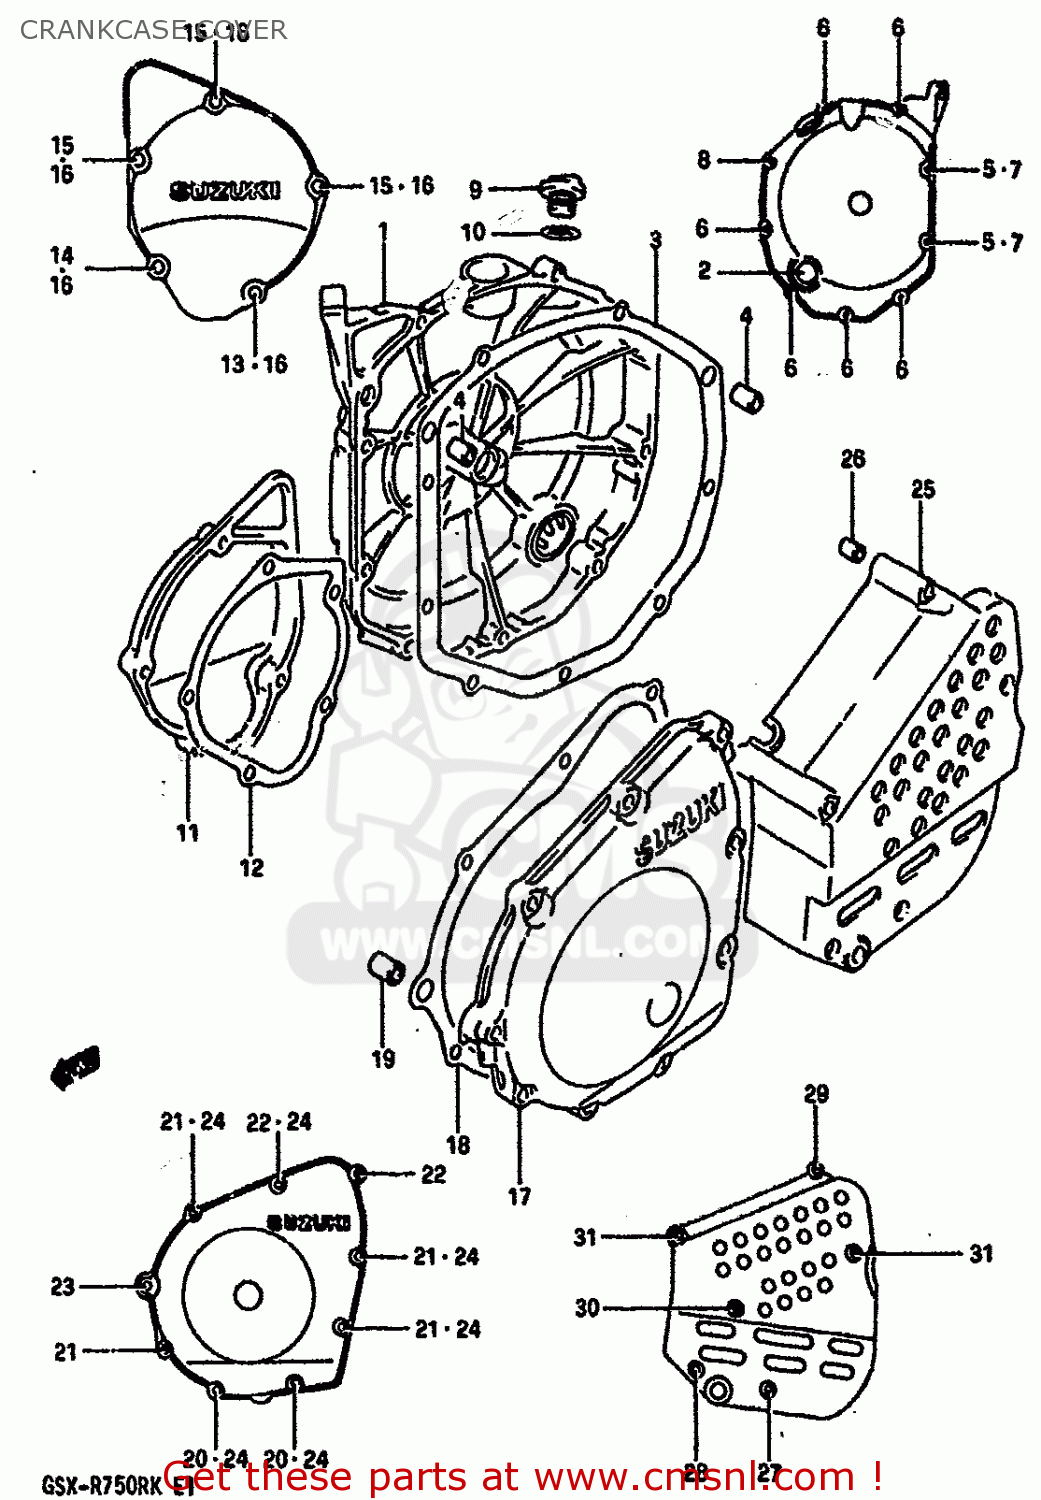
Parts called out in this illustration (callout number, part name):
1	COVER,CLUTCH
2	LENS,OIL LEVEL CHECK
3	GASKET,CLUTCH COVER (MCA)
4	PIN
5	GASKET(5.8X11X1.2) (NAS)
6	BOLT
7	BOLT
8	BOLT
9	PLUG
10	O RING(D:3.1,ID:16.8)
11	COVER,SIGNAL GENERATOR
12	GASKET,SIGNAL
13	BOLT
14	BOLT
15	BOLT
16	GASKET(5.8X11X1.2) (NAS)
17	COVER,STARTER GEAR
18	GASKET,STARTER
19	PIN(11X14)
20	BOLT
21	BOLT
22	BOLT
23	BOLT
24	GASKET(5.8X11X1.2) (NAS)
25	COVER,SPROCKET
26	PIN
27	BOLT
28	BOLT
29	BOLT
30	BOLT
31	BOLT
